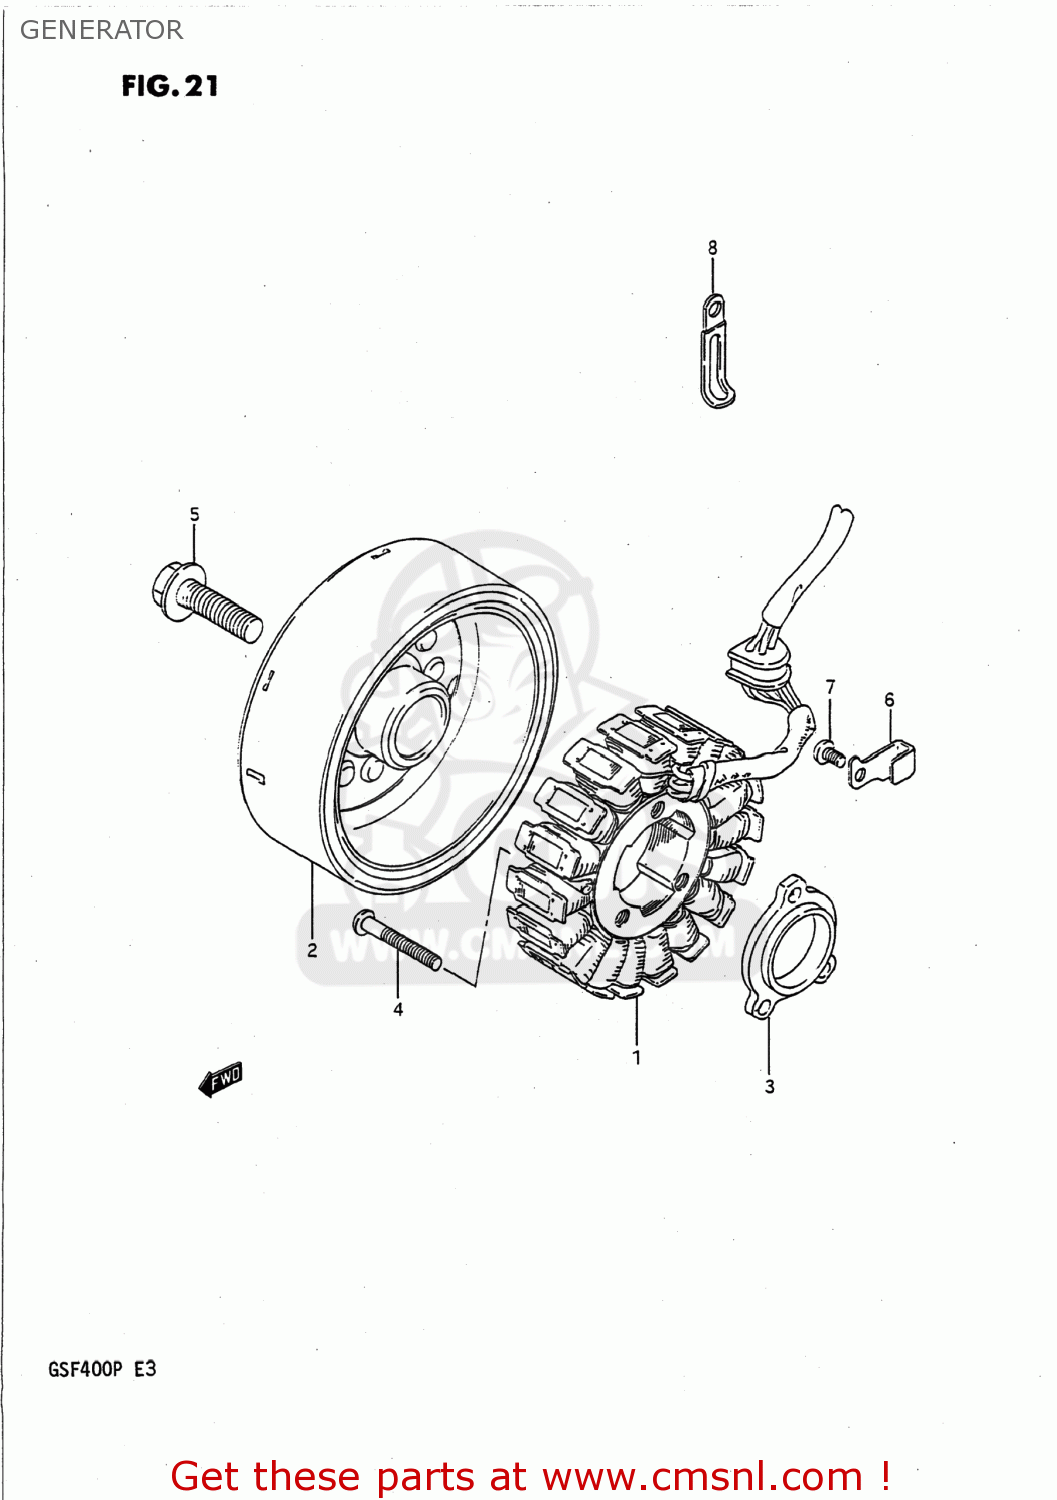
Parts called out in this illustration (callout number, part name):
1	STARTER ASSY
2	ROTOR
3	SPACER,GENERATOR STATOR
4	SCREW
5	BOLT(12X40)
6	CLAMP,GENERATOR LEAD WIRE
7	SCREW
8	CLAMP
